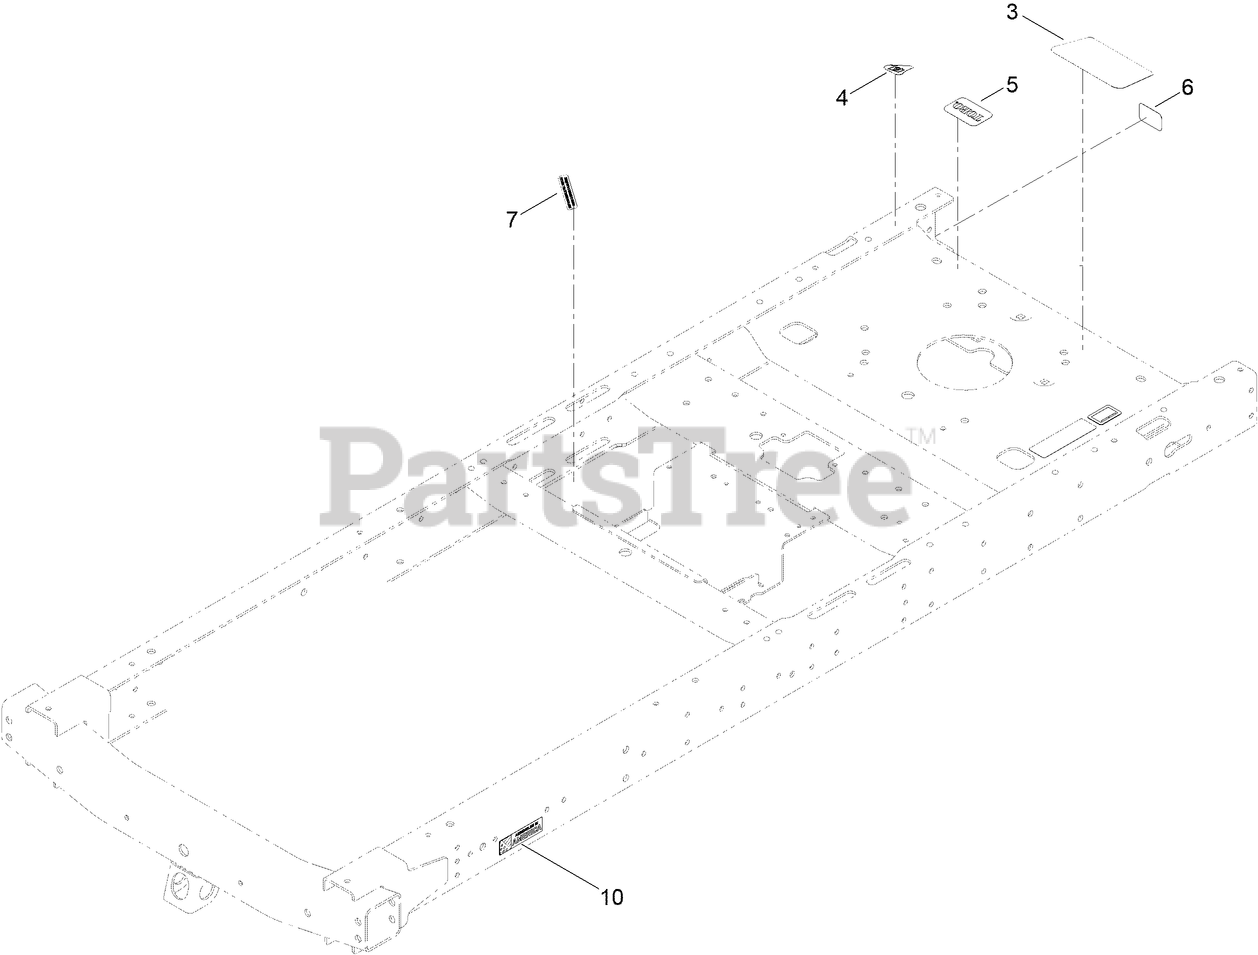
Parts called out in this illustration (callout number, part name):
3	DECAL-ENGINE
4	DECAL-DRAIN, OIL
6	PLACARD-INTAKE
7	DECAL-SHUTDOWN
